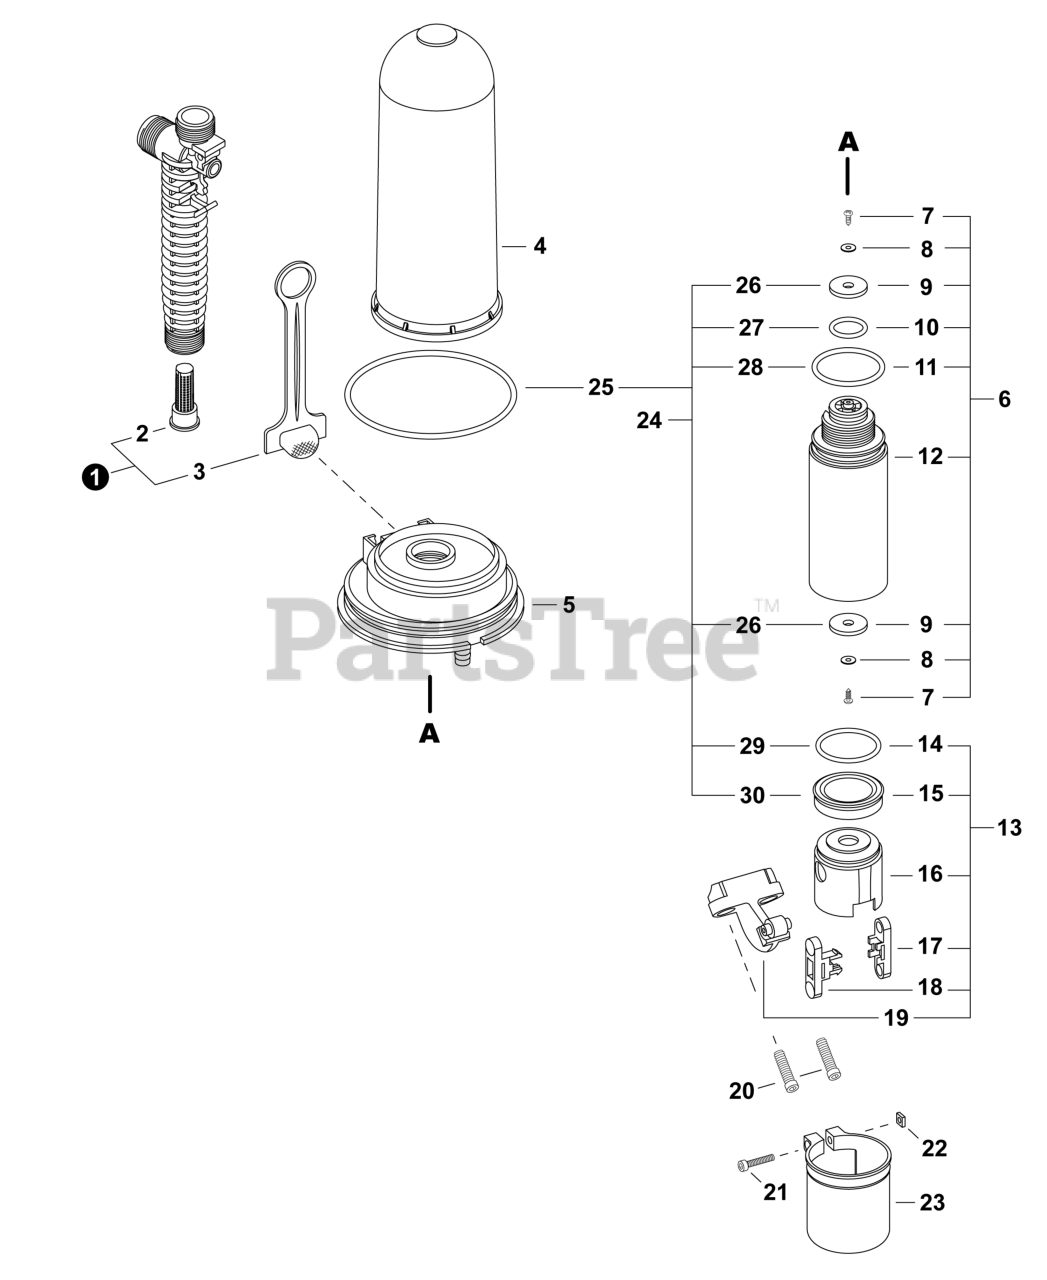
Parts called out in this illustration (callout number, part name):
1	FILTER KIT
2	FILTER, SPRAY GUN
3	FILTER, IN-TANK
4	BASE, PRESSURE CHAMBER
5	BASE, PRESSURE CHAMBER
6	CYLINDER ASSY, PISTON
7	SCREW, CYLINDER
8	WASHER, CYLINDER
9	SEAL, VALVE
10	O-RING, CYLINDER - SMALL
11	O-RING, CYLINDER - LARGE
12	CYLINDER, PISTON
13	PISTON ASSY
14	SPRING, SEAL
15	SEAL, PISTON
16	PISTON
17	ROD, CONNECTING (A)
18	ROD, CONNECTING (B)
19	LEVER, PIVOT
20	SCREW, LEVER
23	CAP, DUST
24	REPAIR KIT, PUMP
25	O-RING, PRESSURE CHAMBER
26	SEAL, VALVE
27	O-RING, CYLINDER - SMALL
28	O-RING, CYLINDER - LARGE
29	SPRING, SEAL
30	SEAL, PISTON
